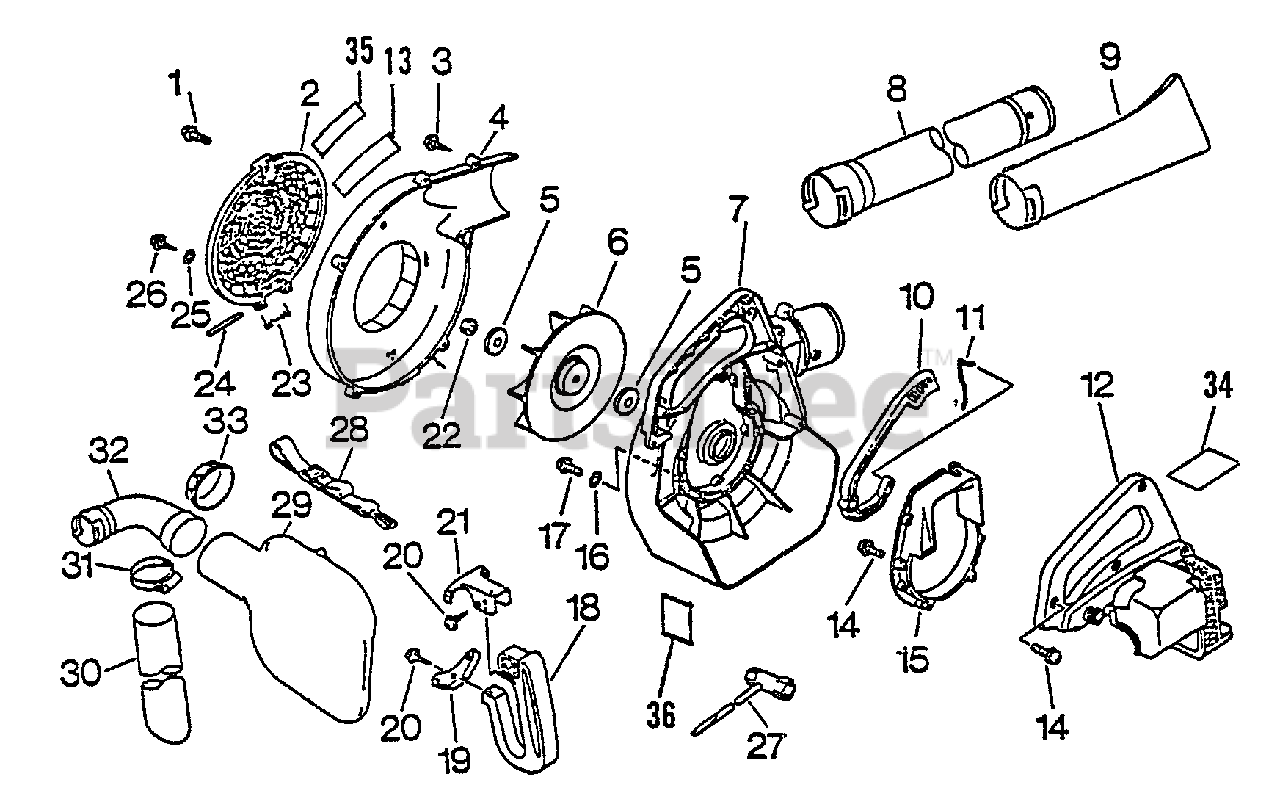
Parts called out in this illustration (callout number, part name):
1	THUMBSCREW
2	SHIELD, DEBRIS
3	SCREW, TAPPING 5×20
4	COVER, FAN - LEFT
6	FAN
7	COVER, FAN - RIGHT
8	TUBE, BLOWER - STRAIGHT
9	NOZZLE - FAN HEAD
10	TRIGGER, THROTTLE
11	ROD, THROTTLE
12	COVER, ENGINE
13	LABEL, MODEL
14	SCREW 4×18
15	BRACKET, ENGINE
17	SCREW 4×22
19	BRACKET, LOWER HANDLE
20	SCREW 5×14
21	BRACKET, UPPER HANDLE
23	SPRING, COIL
24	PIN, INTAKE COVER
26	SCREW 5×14
27	T-WRENCH 13×19×180
29	BAG, DUST
30	ADAPTER, TUBE
34	LABEL - CAUTION -- HOT
35	LABEL - NOISE
36	LABEL, CAUTION - HOT
